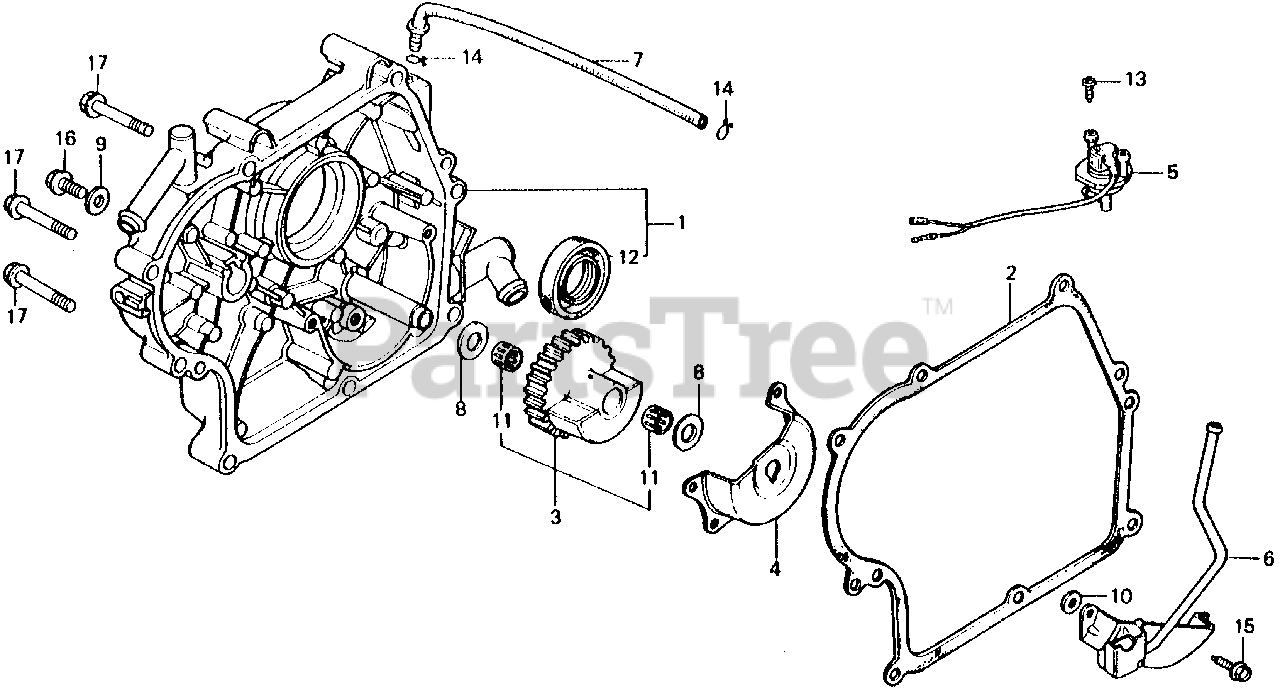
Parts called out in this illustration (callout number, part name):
1	COVER ASSY., CRANKCASE
2	GASKET, CASE COVER
3	WEIGHT, BALANCER
4	COVER, BALANCER
5	SWITCH ASSY., UNIT
7	TUBE, OIL ALERT
8	WASHER, THRUST (15MM)
9	WASHER A (8MM)
10	WASHER, CRANK ARM
11	BEARING, NEEDLE
12	OIL SEAL (30X46X8)
13	SCREW, TAPPING (5X10)
14	CLIP, TUBE (C11)
15	BOLT, FLANGE (6X16)
16	BOLT, FLANGE (8X12)
17	BOLT, FLANGE (8X45)
